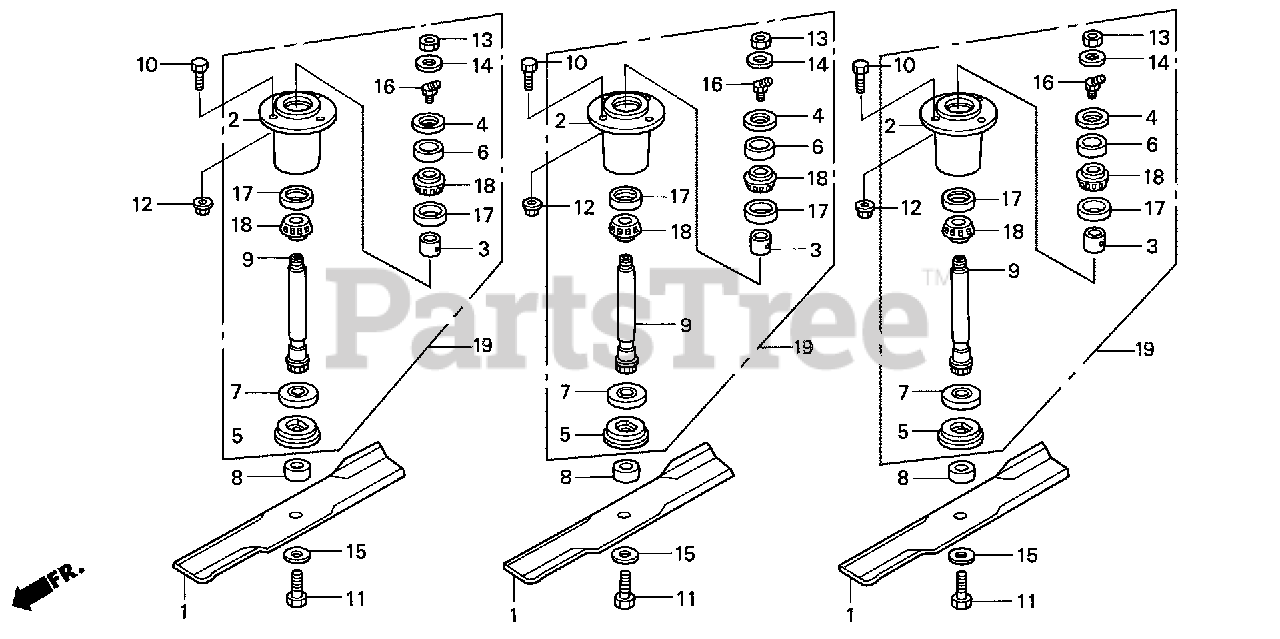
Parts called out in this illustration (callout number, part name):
1	BLADE, HIGH LIFT (16.5")
2	HOUSING, BEARING
3	SPACER, BEARING (1 1/4"OD X 1 1/4")
4	SEAL, SPINDLE (UPPER)
5	SPACER, BLADE
6	SPACER, SEAL
7	SEAL, SPINDLE (LOWER)
8	SPACER, BLADE (3/8")
9	SHAFT, BLADE
10	BOLT, HEX. (3/8-16X1 1/4")
11	BOLT, HEX. (5/8-18X1 3/4")
12	NUT, WHIZ-LOCK (3/8"-16)
13	NUT, JAM (5/8"-18)
14	WASHER (5/8"-1 5/16")
15	WASHER, FLAT (5/8")
16	NIPPLE, GREASE (1/4 "28 45)
17	BEARING, CUP
18	BEARING, CONE
19	SPINDLE ASSY.
